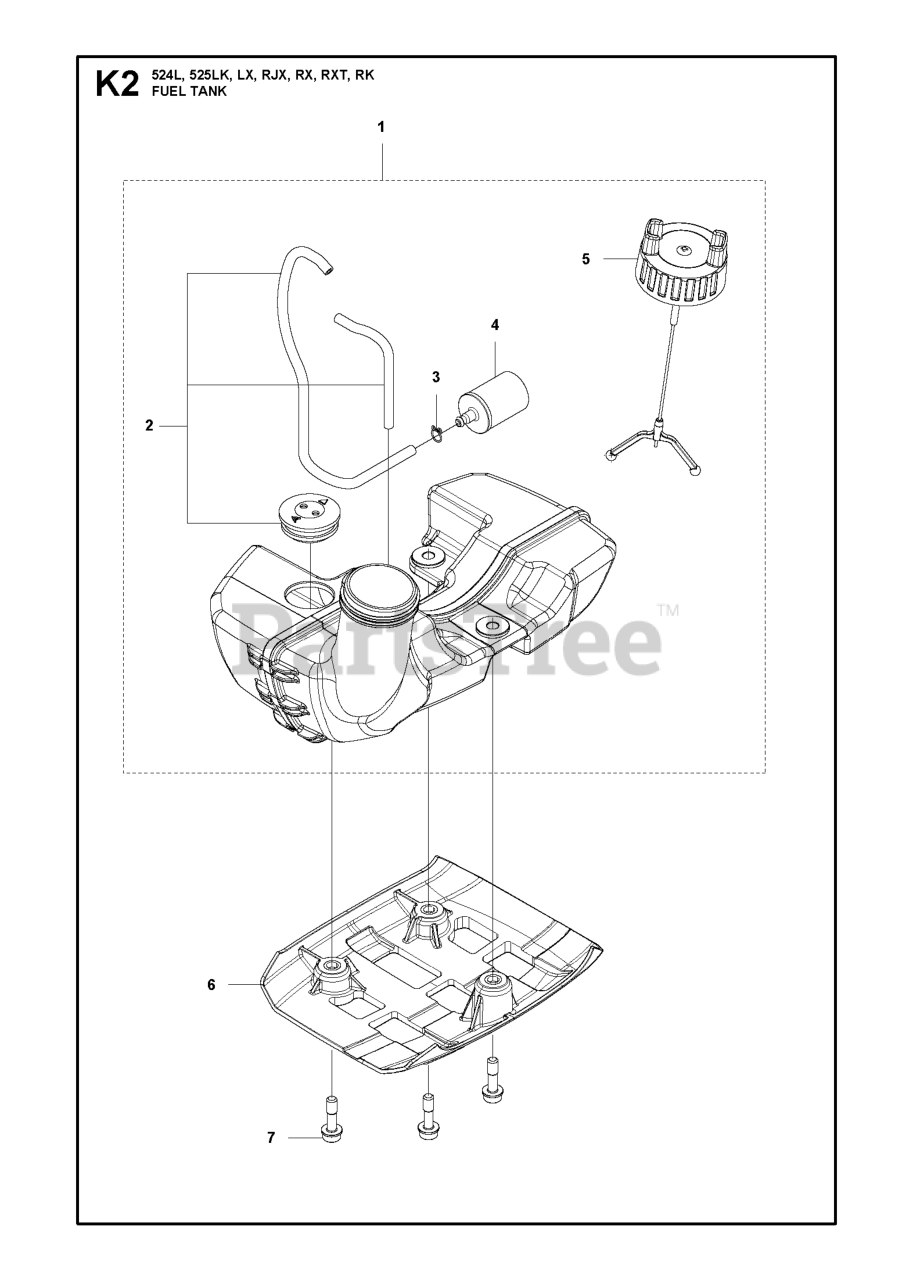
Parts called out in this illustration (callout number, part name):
4	RP FUEL FILTER
6	SKID PLATE
7	BOLT
